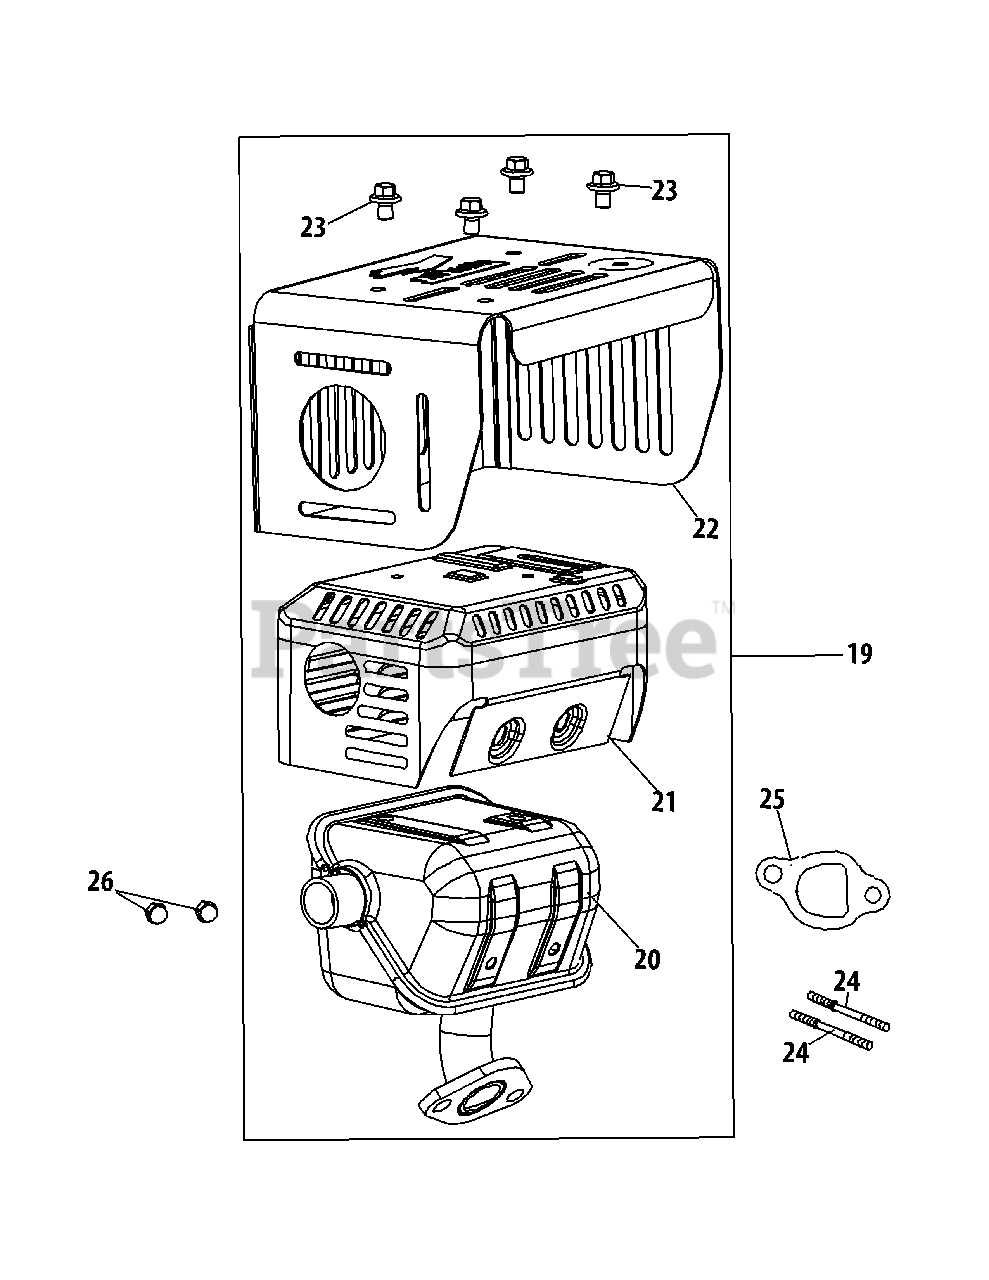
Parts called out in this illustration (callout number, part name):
19	Muffler Assembly
20	Muffler Body
21	Muffler Shield
22	Muffler Guard
23	Bolt M5×8
24	Stud M8×34
24	Muffler Stud Assy
25	Exhaust Pipe Gasket
26	Nut, M8
